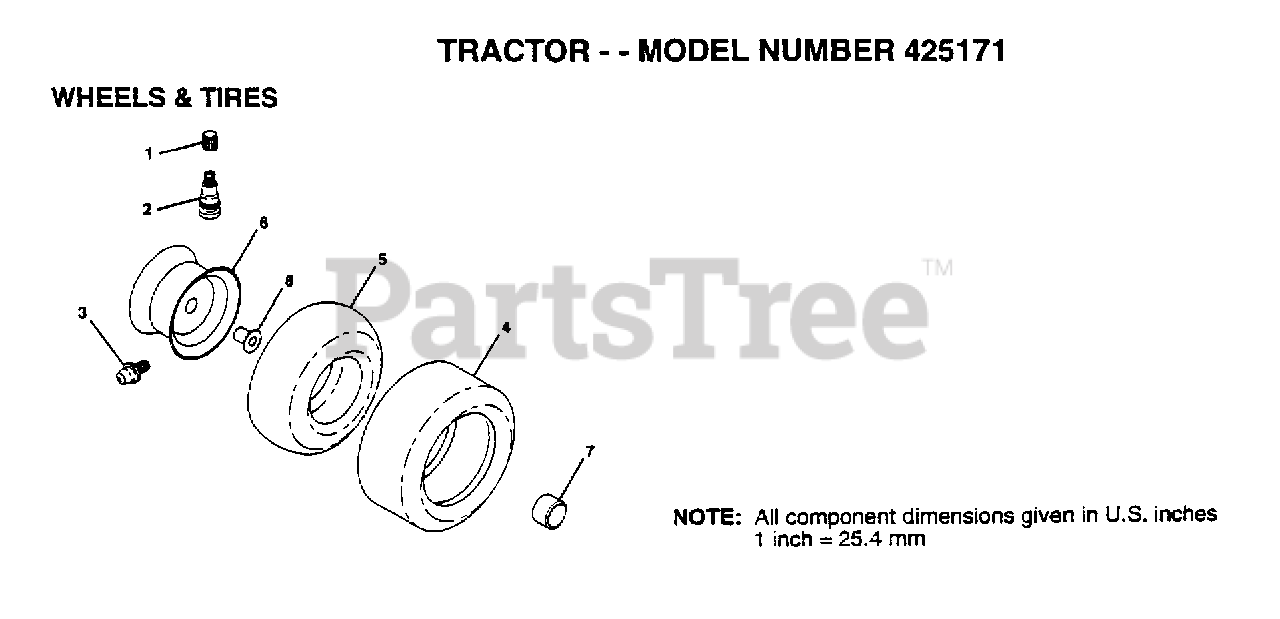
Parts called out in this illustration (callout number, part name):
1	VALVE CAP
2	VALVE STEM LT
3	FITTING LT
4A	TIRE.20X8-8
5	TUBE.5.3/4.5/6
5A	TUBE.18X9.5-8
6	"RIM,FRT T"
6A	"RIM 8"""
7	HUB CAP
8	"FLANGE, BEARING"
